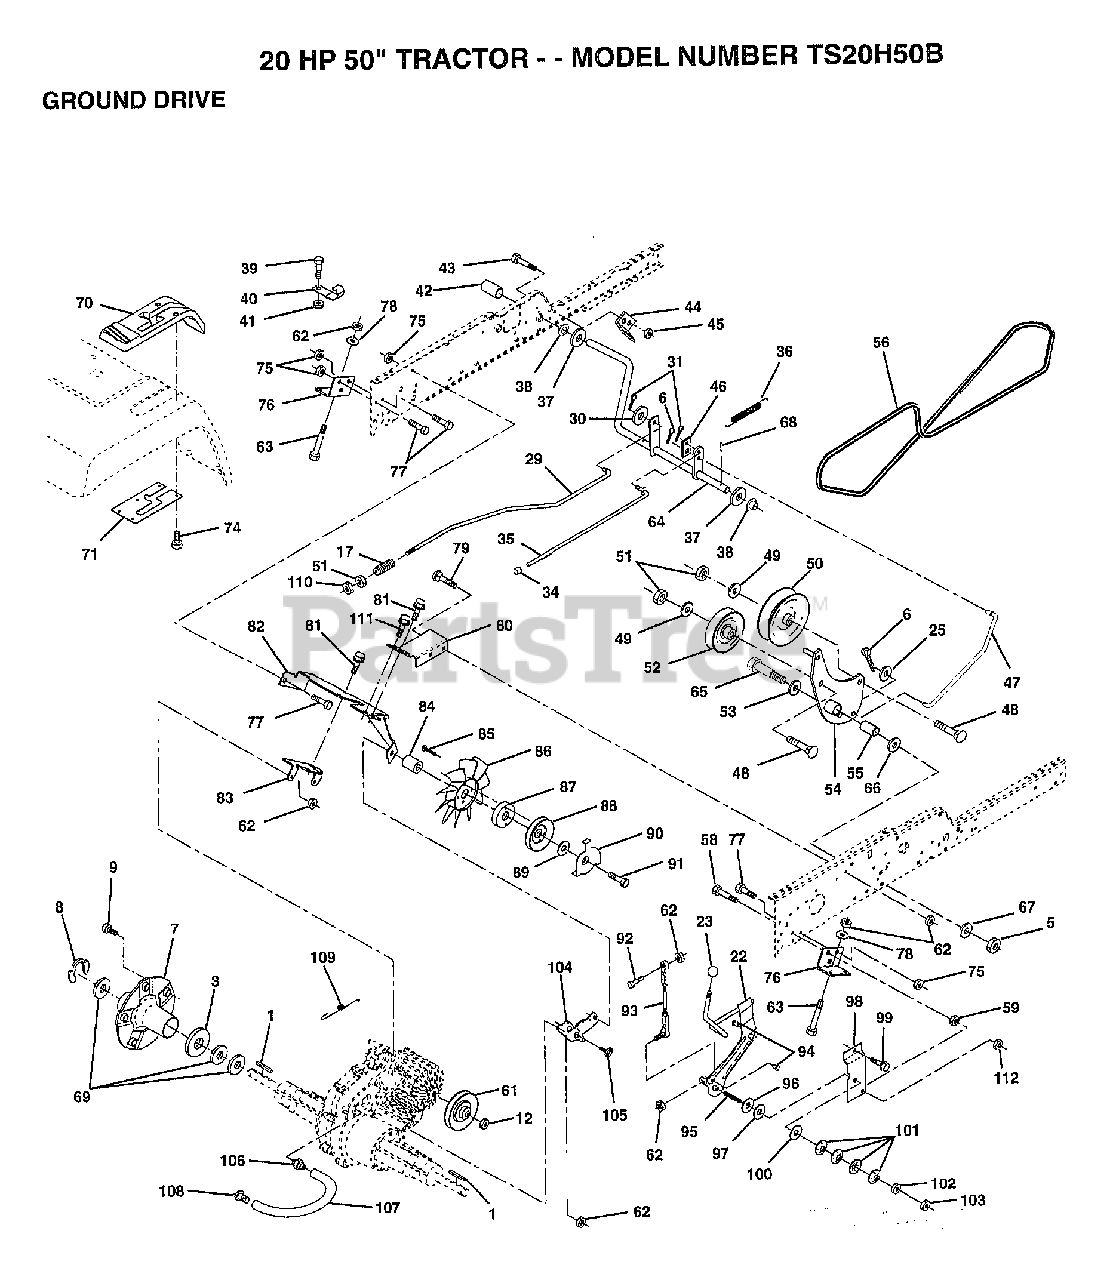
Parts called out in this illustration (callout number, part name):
1	KEY 1/4 X 2.5
3	WASHER T
6	COTTER PIN
7	HUB WHEEL ASM
8	E RING HYT
9	BOLT.HUB.WHL.REAR
17	SPRING ROD BRAKE
22	SHAFT ARM ASM
23	KNOB.DUCKHEAD.1/2
25	WASHER
29	ROD BRAKE
30	WASHER
34	PLUNGER CAP T
35	ROD BRAKE PART GT
37	WASHER
38	NYLINER T
39	SCREW
40	ACT-SWITCH T
42	PEDAL COVER T
43	BOLT LT
44	BRKT SWITCH GT
45	NUT
46	RETAINER SPRING
47	ROD.CLUTCH
48	BOLT
49	WASHER
50	FLAT IDLER PULLEY
51	NUT
52	PULLEY.IDLER.V.GR
53	WASHER T
54	ARM.ASM.IDLER.CLU
55	"LY, BEARING"
56	BELT-V 84.5
58	BOLT
59	NUT
61	PULLEY TRANSAXLE
62	NUT
63	BOLT FIN HEX 5/16
65	AXLE BOLT
66	WASHER.HARD.BLADE
67	WASHER
68	ROLL PIN STD
69	WASHER T
71	PLATE CONSOLE S
74	SCREW HEXWSH H-L
75	NUT.7/16
76	BRACKET TRAN VGTH
77	BOLT
78	WASHER
79	BOLT
80	BRACKET TORQUE RH
81	SCREW
83	STRAP TORQUE MID
84	SPACER
85	SCREW YTV
86	"FAN 7"" HYDRO"
87	ADAPTER FAN
89	WASHER
90	KEEPER BELT
91	SCREW.HXWSH.3/8
93	LINK ASM SHIFT
94	XMAS TREE FASTNER
95	SCREW SET 5/16
96	WASHER NICKEL PLT
97	BEARING THRUST
98	BRACKET SHIFT
99	SCREW LT
100	WASHER COMPRESSIN
101	WASHER
102	NUT HEX NYLOCK
103	JAM NUT TI
104	BRACKET IDLER
105	SCREW CRT
109	SPRING BRAKE
110	NUT
111	HINGE SCREW
112	NUT GTV
